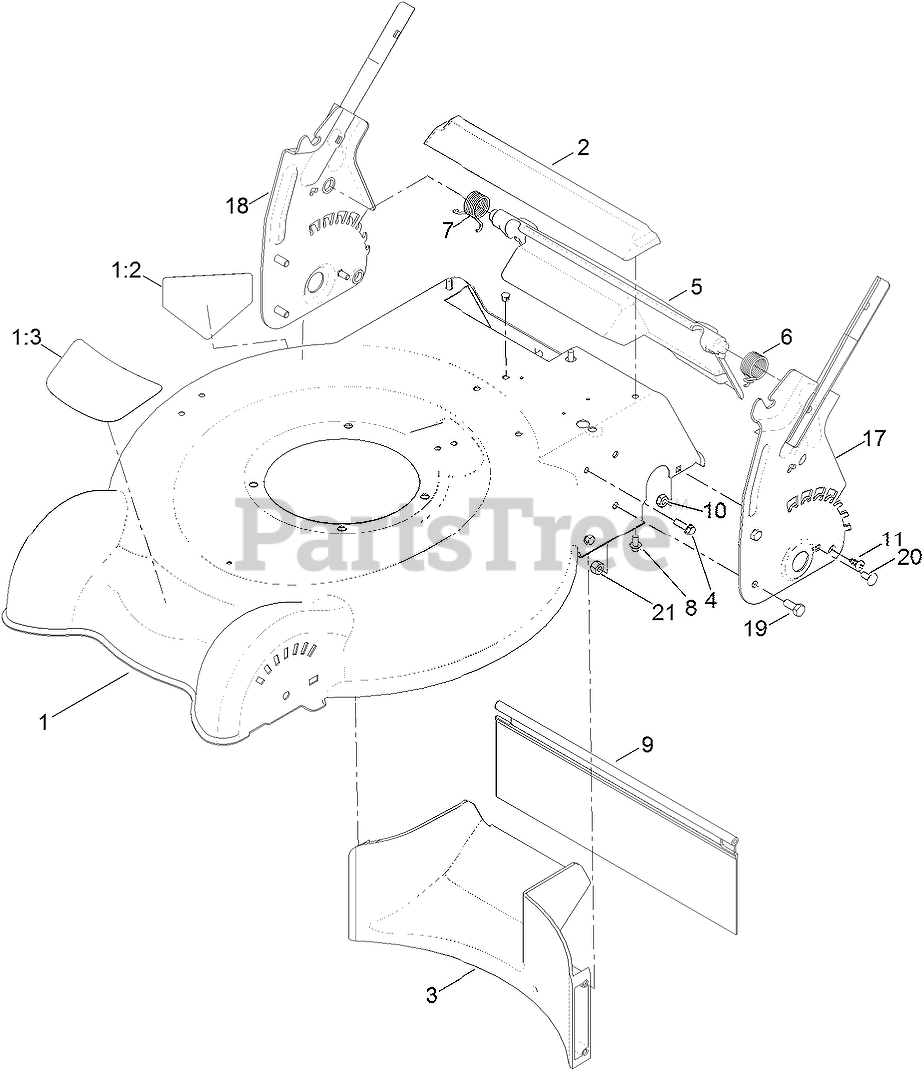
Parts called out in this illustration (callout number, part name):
1	HOUSING ASM
1:2	DECAL-DANGER
1:3	DECAL-DECK
2	CHUTE-REAR
3	BAFFLE-REAR
4	SCREW-HWH
5	Rear Deflector ASM
6	SPRING-TORSION, LH
7	SPRING-TORSION, RH
8	SCREW-PLASTITE
9	SHIELD-TRAILING
10	NUT-LOCK, NI
11	SCREW-PTH
19	SCREW-HH
20	SCREW-CARR
21	NUT-LOCK, NI
